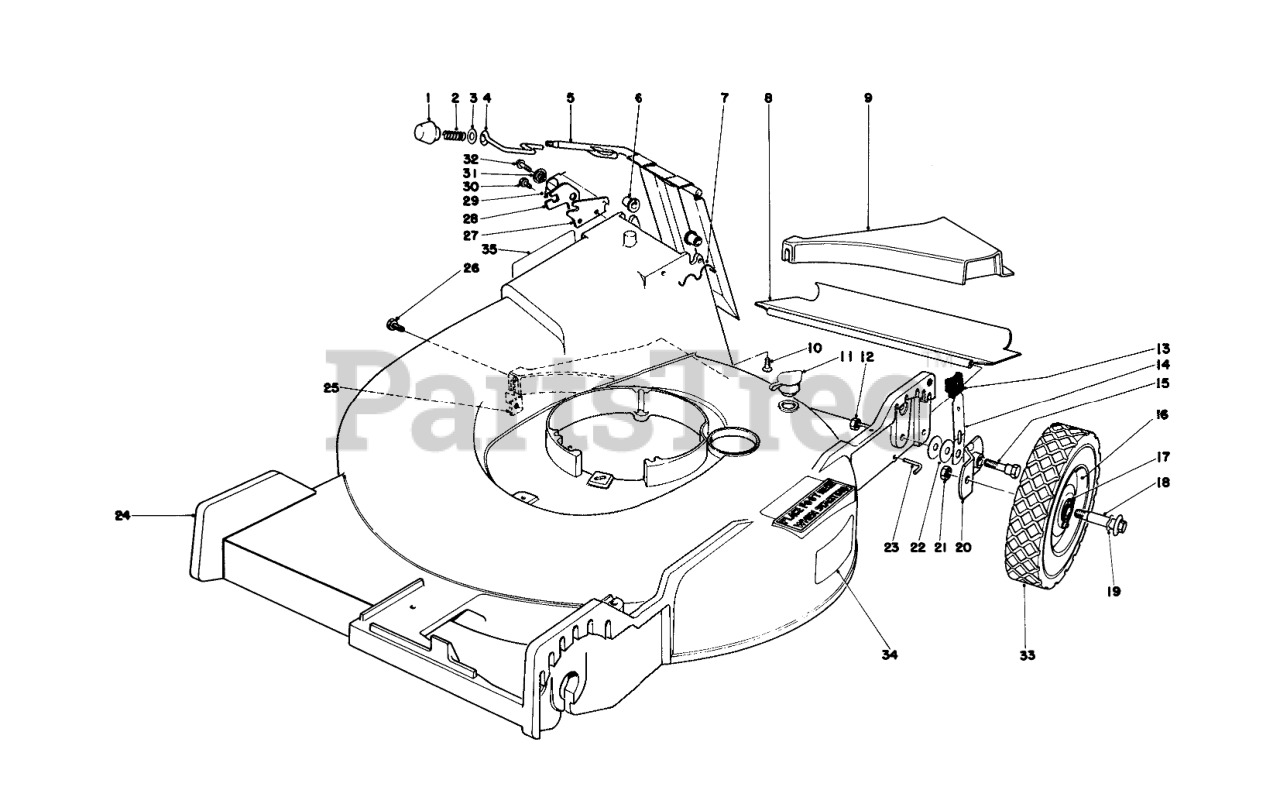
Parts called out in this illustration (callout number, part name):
2	COMPRESSION SPRING
3	WASHER
4	DOOR LATCH
5	Door Handle
6	BUSHING-NYLON
7	Door Retainer
8	REAR SAFETY SHIELD
9	REAR INSERT
10	SCREW-HH
11	WASHOUT PLUG
12	Nut
13	KNOB-ARM
14	SPRING ARM ASM
15	PIVOT SCREW
16	Wheel & Tire Assy. (Incl. Ref.#4)
17	BEARING-BALL
19	SPRING WASHER
20	PIVOT ARM ASM A
21	Nut
22	WASHER-PIVOT
23	ROD-SHIELD
24	Housing
25	SPECIAL NUT
26	SCREW THD 1/4 20 5/8
27	DOOR LATCH PLATE
28	Latch Safety
29	TORSION SPRING
30	Screw
31	Latch Spacer
32	Screw
34	Decal Step
35	Decal Caution
